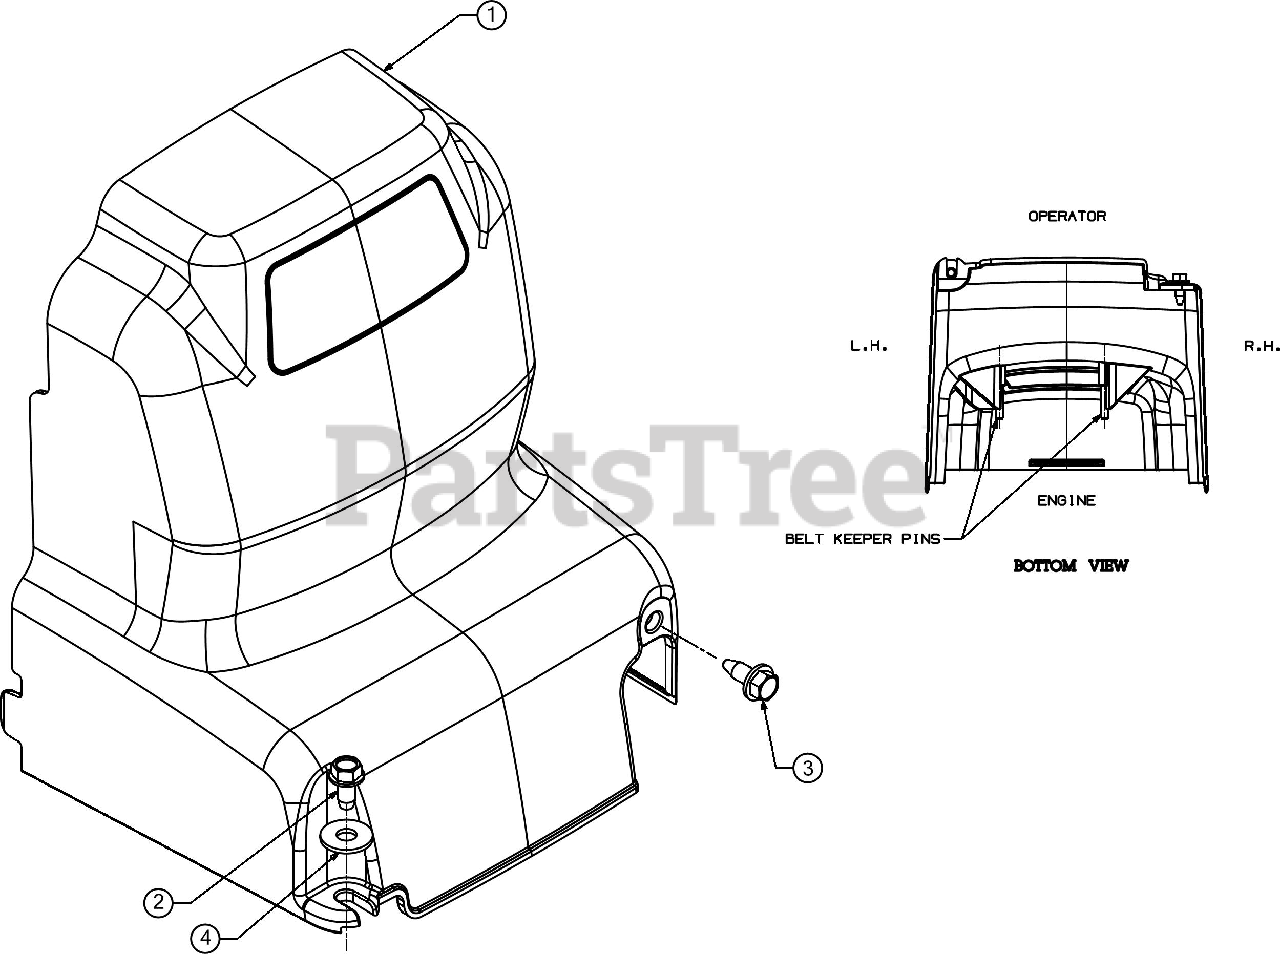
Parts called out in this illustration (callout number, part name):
1	COVER-BELT 400 SERIES TILLER
2	SCREW 1/4-20 X.500
3	SCREW 1/4-14 x .625
4	FLAT WASHER .28 ID x .74 OD x .063
